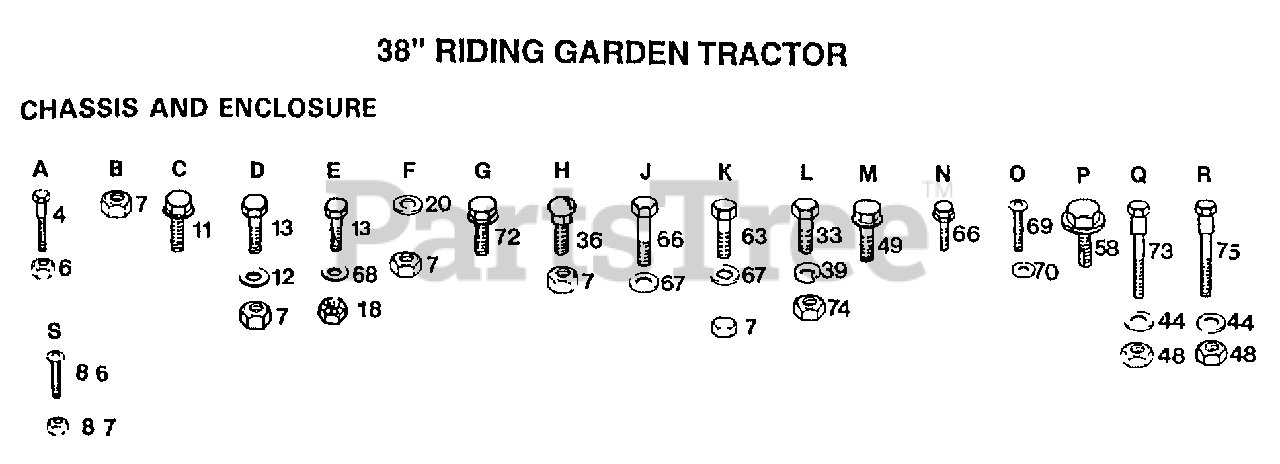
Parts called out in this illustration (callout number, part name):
11	SCREW
12	WASHER
18	NUT
20	WASHER
33	BOLT LT
36	BOLT
39	LOCKWASHER
49	SCREW LT
63	BOLT
66	SCREW GTV
67	WASHER HYT
68	WASHER
69	SCREW
73	BOLT T
75	SHOULDER BOLT ST
87	"NUT,KEPS"
